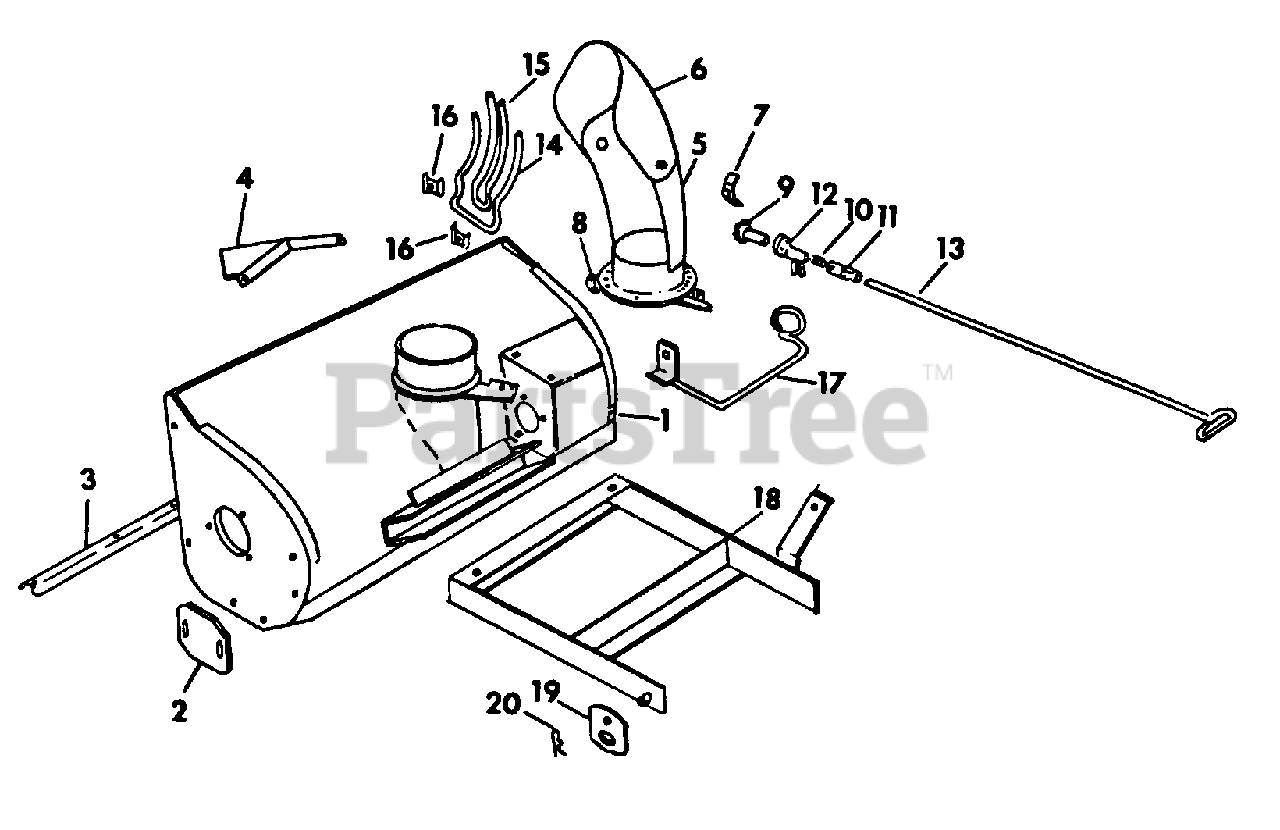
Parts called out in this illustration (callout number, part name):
1	Housing Assy, Welded
3	Blade, Scraper
4	Guard, Deflector
5	Chute Assy, Welded
6	Cap, Deflector
8	Clip, Retainer
9	Sprocket, Chute Adjusting -12 Teeth- -Replaces 397 041 R1
11	Joint Assy, Universal
12	Support, Brg
13	Rod, Chute Control
14	Rod, Chute Deflector Side
15	Rod, Chute Deflector Center
17	Bracket, Chute Control Rod
18	Bracket, Lift
19	Clip, Retainer
20	Pin, Lift Bracket Hair
